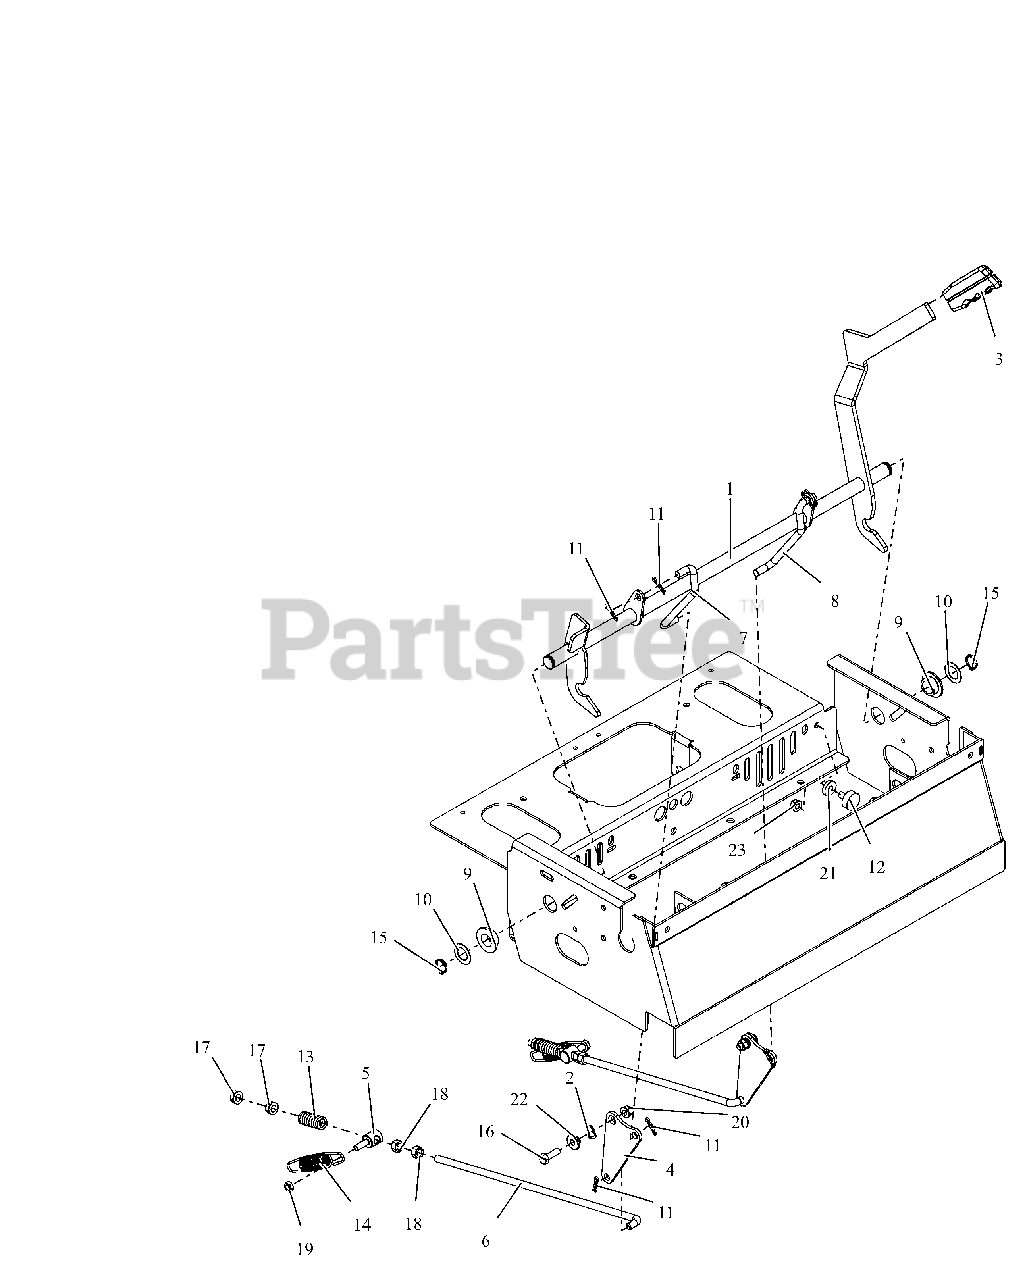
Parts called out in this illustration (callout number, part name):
1	WLDMT, PT200/400 PARK BRAKE
2	WAVE WASHER .531X.781X.125FH
3	GRIP, PARKING BRAKE (YELLOW)
4	PLATE, BRAKE PIVOT
5	TRUNNION, .38-16
6	ROD, BRAKE ADJ.
7	LINKAGE, RH BRAKE ACTUATING
8	LINKAGE, LH BRAKE ACTUATING
9	BSHG-FLG .762X1.48X.44 NYL
10	WSHR-HDND-THRST .758X1.23X.031
11	PIN, HAIR #225 .072X1.09
12	BUMPER, RUBBER
13	SG-COMP .142 X .710 X 1.75
14	SPRING-TENS .105X.850X.4.880
15	RG-RTNG-EXT .689X.078
16	BLT,HEX .31-18X1.00 G5 ZCC
17	NUT, SPNLK-FLG .38-16 G5 ZCC
18	NUT-STD .375-16 G2 ZCC
19	NUT-LK-CTR-JAM .312-18 GB ZCC
20	NUT-LK-TOP-FLG .312-18 GF ZCC
21	WSHR, FLT .328X.870X.179 ZCC
22	BSHG-FLG .32X.500X.344X.880
23	NUT,SPNLK-FLG .31-18 G5 ZCC
